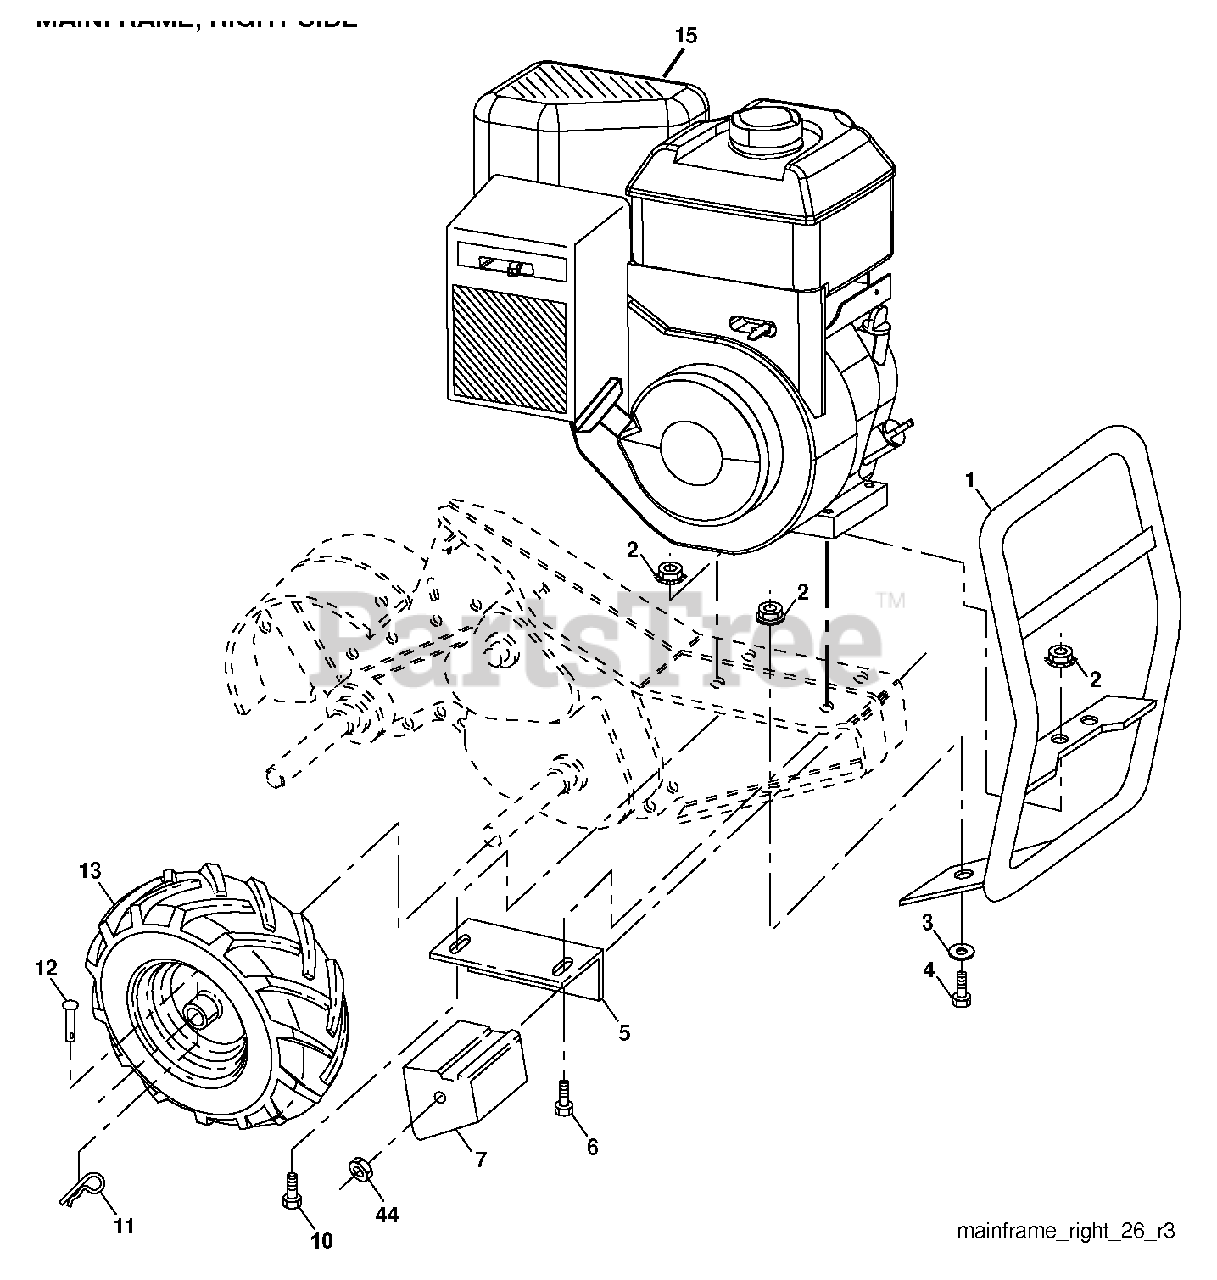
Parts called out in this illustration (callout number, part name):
1	BUMPER.ASM.REAR.TILLER.479
2	LOCKNUT-FLANGE 5/16-18
3	WASHER
4	BOLT
5	BRACKET.REINFORCEMENT.RH.BLACK
6	BOLT, HEX 5/16-18X1-3/4
7	COUNTERWEIGHT.RH
10	BOLT
11	RETAINER M
12	RIVET
13	WHEEL.ASM.DRT.13X5-6.RT.SILVER
